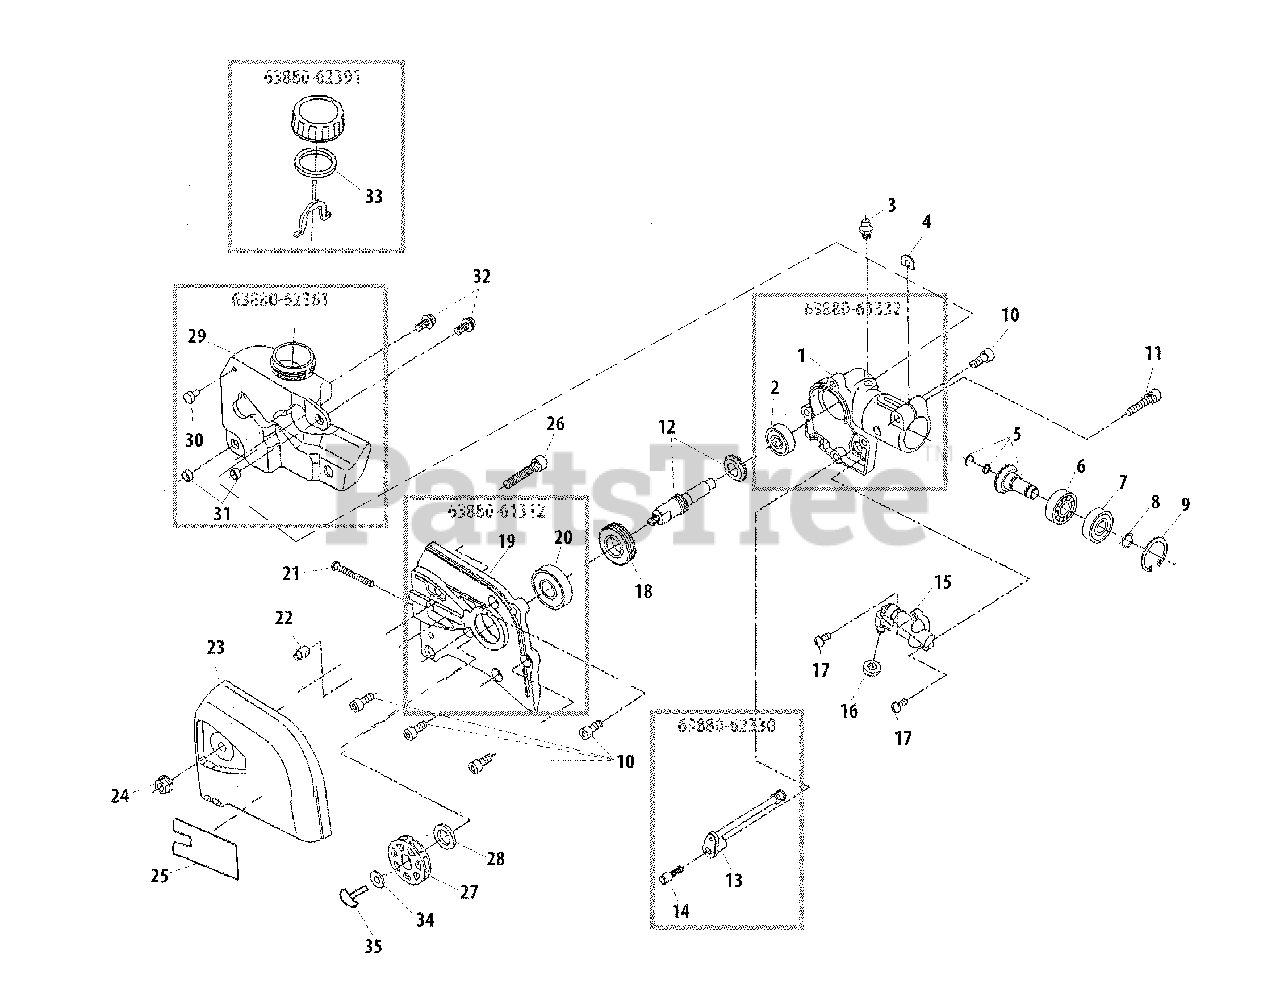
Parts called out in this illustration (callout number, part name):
1	GEAR CASE, RIGHT
2	BEARING, BALL 627ZZ
3	FITTING, GREASE
4	D-WASHER
5	PINION, BEVEL
6	BEARING, BALL 609
7	BEARING, BALL 609ZZ
8	RING, SNAP
9	RING, SNAP Ø24
10	BOLT 5×12
11	BOLT M5×25
12	GEAR SET, BEVEL
13	PIPE, OIL
14	FILTER, OIL
15	OIL PUMP ASSY
16	GASKET, AUTO-OILER
17	SCREW
18	GEAR, WORM
19	GEAR CASE, LEFT
20	BEARING, BALL 6001 DDU
21	SCREW - 4×35
22	TENSIONER, CHAIN
23	COVER, SPROCKET
24	NUT, FLANGE M6
25	LABEL, CAUTION
26	BOLT 4×10
27	SPROCKET, DRIVE
28	COLLAR 12
29	TANK, OIL
30	VENT ASSY
32	SCREW M5×12
33	GASKET, CAP
34	WASHER M6
35	SCREW, BUTTON
63880-61312	COVER, GEAR CASE
63880-61332	GEAR CASE HOUSING ASSY
63880-62330	PIPE ASSY, OIL
63880-62361	TANK ASSY, OIL
63880-62391	CAP ASSY, OIL
